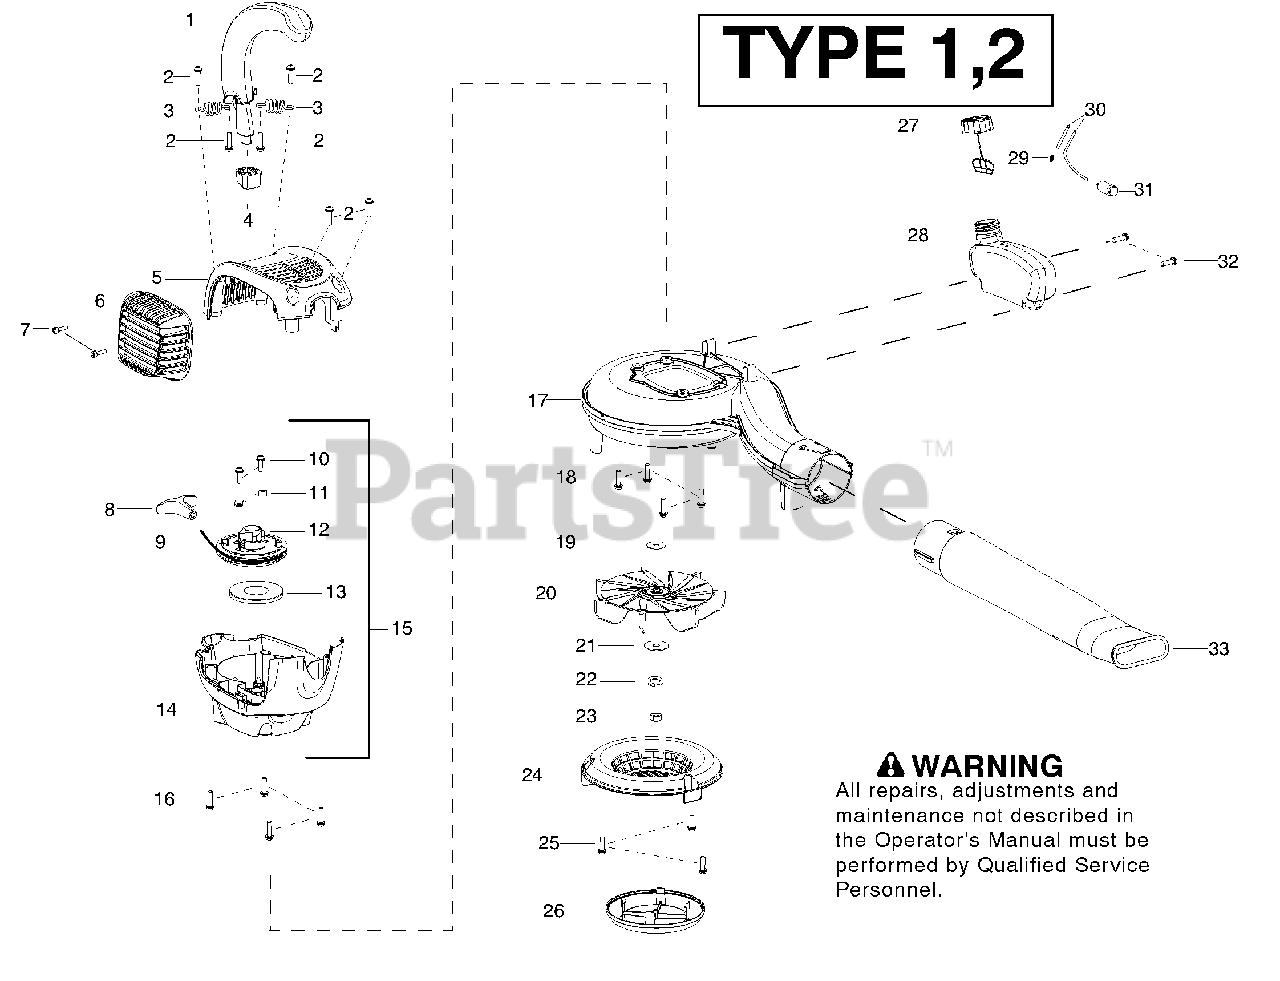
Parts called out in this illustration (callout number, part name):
1	Assy - Handle
3	Spring - Isolator
4	Isolator - Handle
5	Housing - Upper Engine
6	Assy - Muffler Guard
8	Handle - Starter
9	Kit - Rope
10	Screw - Retainer
11	Retainer
12	Kit - Starter Pulley
13	Spring - Starter
14	Assy - Lower end housing with bearing
15	Assy - Lower Engine Housing
16	Screw
17	Assy - Scroll Housing
20	Assy - Impeller
21	Washer - Impeller
22	Washer - Lock
24	Cover - Inlet
26	Deflector - Intake
27	Cap - Fuel (w/retainer)
28	Assy - Fuel Tank
29	Fitting - Fuel Line
30	Kit - Fuel Line
31	Assy - Fuel Pick-up
33	Tube - Blower
